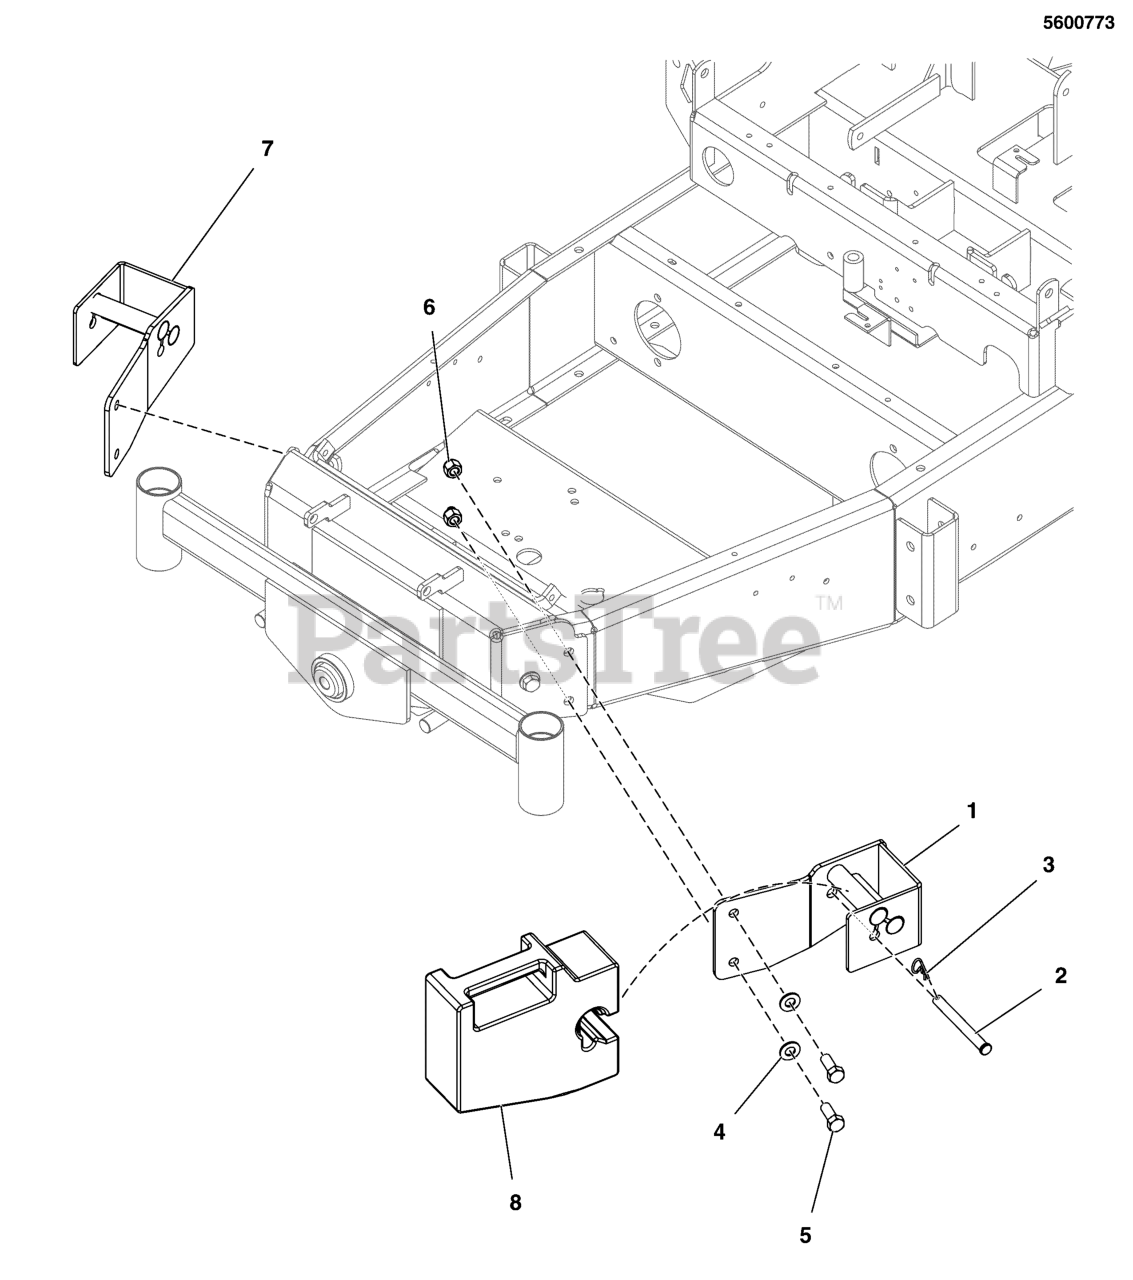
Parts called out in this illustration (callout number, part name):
1	WELD, WEIGHT BRACKET, RH, 800 - BLK
2	PIN CLEVIS 1/2" X 4-1/2" PLT
3	PIN, HAIR, .0915 X 1-7/8
4	WASHER, 1/2 SAE
5	BOLT, 1/2-20 X 1-1/2, GD5 CZ
6	NUT, Hex, Nylon Lock, 1/2-20
7	WELD, WEIGHT BRACKET. S800
8	WEIGHT-QUICK ATTACH 50LB SUITCASE PAINTED
